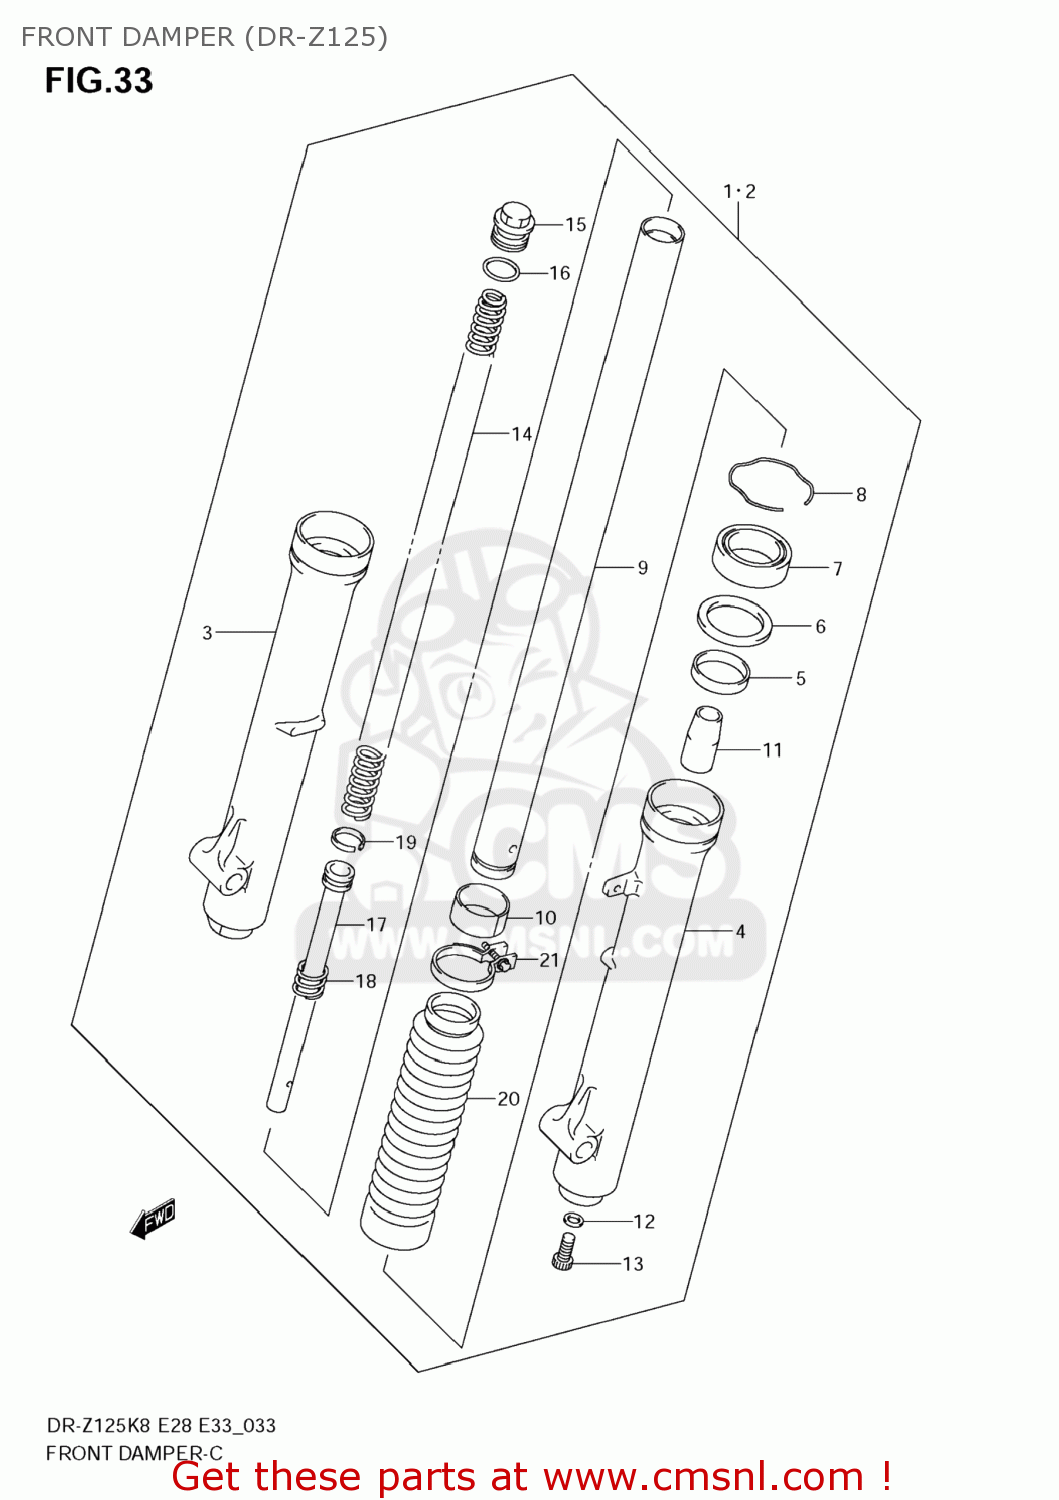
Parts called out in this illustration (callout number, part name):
1	DAMPER ASSY,FR FORK,R
2	DAMPER ASSY,FR FORK,L
3	TUBE,OUTER,R
4	TUBE,OUTER,L
5	BUSH,GUIDE
6	SPACER,SEAL
7	SEAL,OIL
8	SEAL,OIL STOPPER RING
9	TUBE,INNER
10	BUSH,SLIDE
11	PIECE,OIL LOCK
12	GASKET (NAS)
13	BOLT(8X27)
14	SPRING,FR
15	BOLT
16	O RING
17	CYLINDER
18	SPRING,REBOUND
19	RING
20	BOOT
21	BAND
